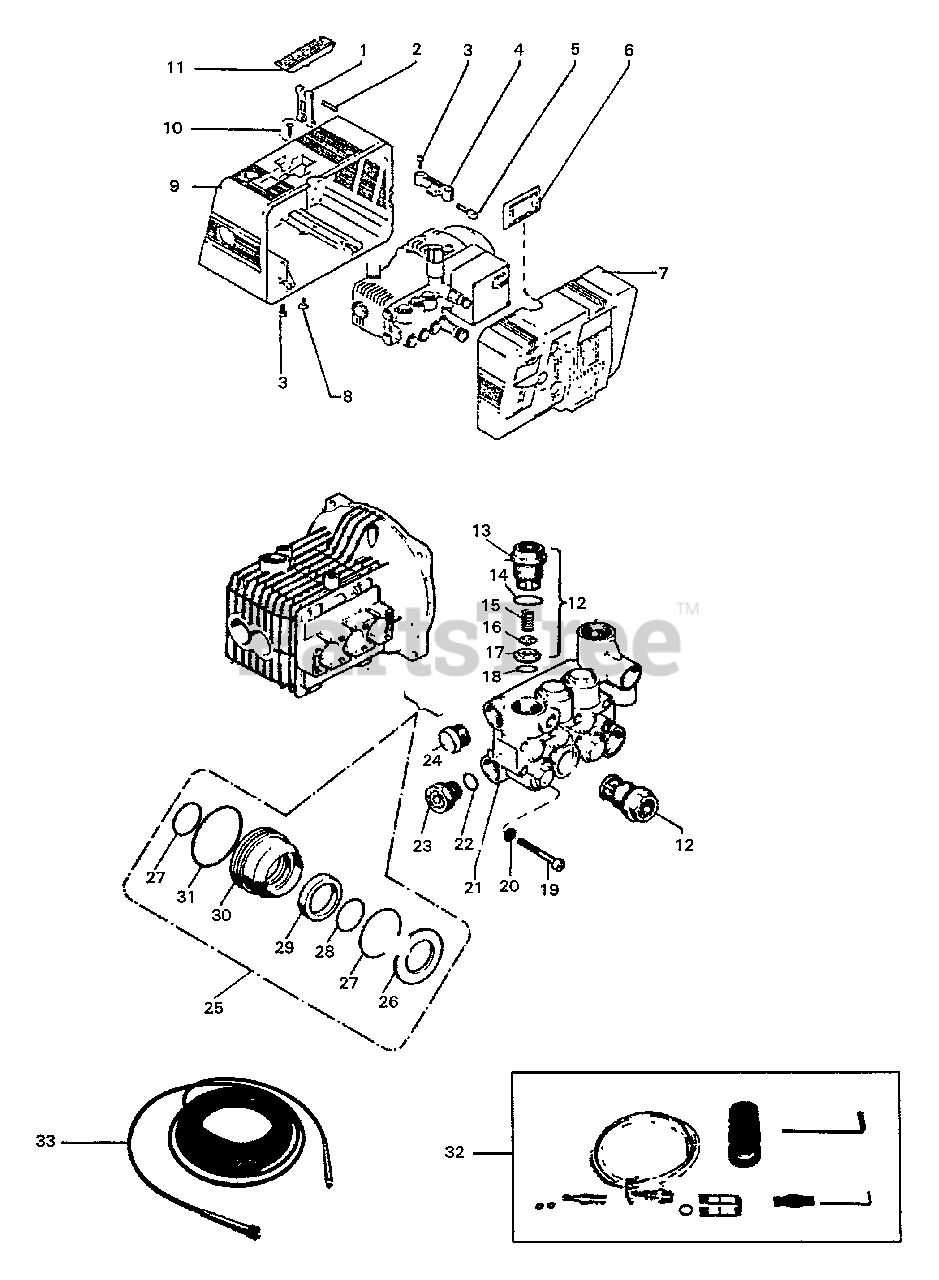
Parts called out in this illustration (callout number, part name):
1	ARM, HANDLE
2	PIN, 8.5 X 34
3	SCREW - 8X16
4	PLATE, HANDLE RETAINER
5	PIN, HANDLE RETAINER
6	SWITCH, IGNITION
7	COVER - FRONT
8	PLUG
9	COVER - REAR
10	SCREW - 4X13
11	HANDLE
12	VALVE KIT
13	CAP, VALVE
14	O-RING
15	SPRING, VALVE
16	PLATE
17	SEAT, VALVE
18	O-RING
19	SCREW - 6X40
20	LOCKWASHER - 6
21	MANIFOLD
22	O-RING
23	PLUG
24	CAP, OIL DRAIN PLUG
25	RETAINER REBUILD PACKING KIT
26	WASHER
27	O-RING
28	O-RING
29	PACKING
30	PACKING, RETAINER
31	O-RING
32	ACCESSORY KIT
33	HOSE - 8M
